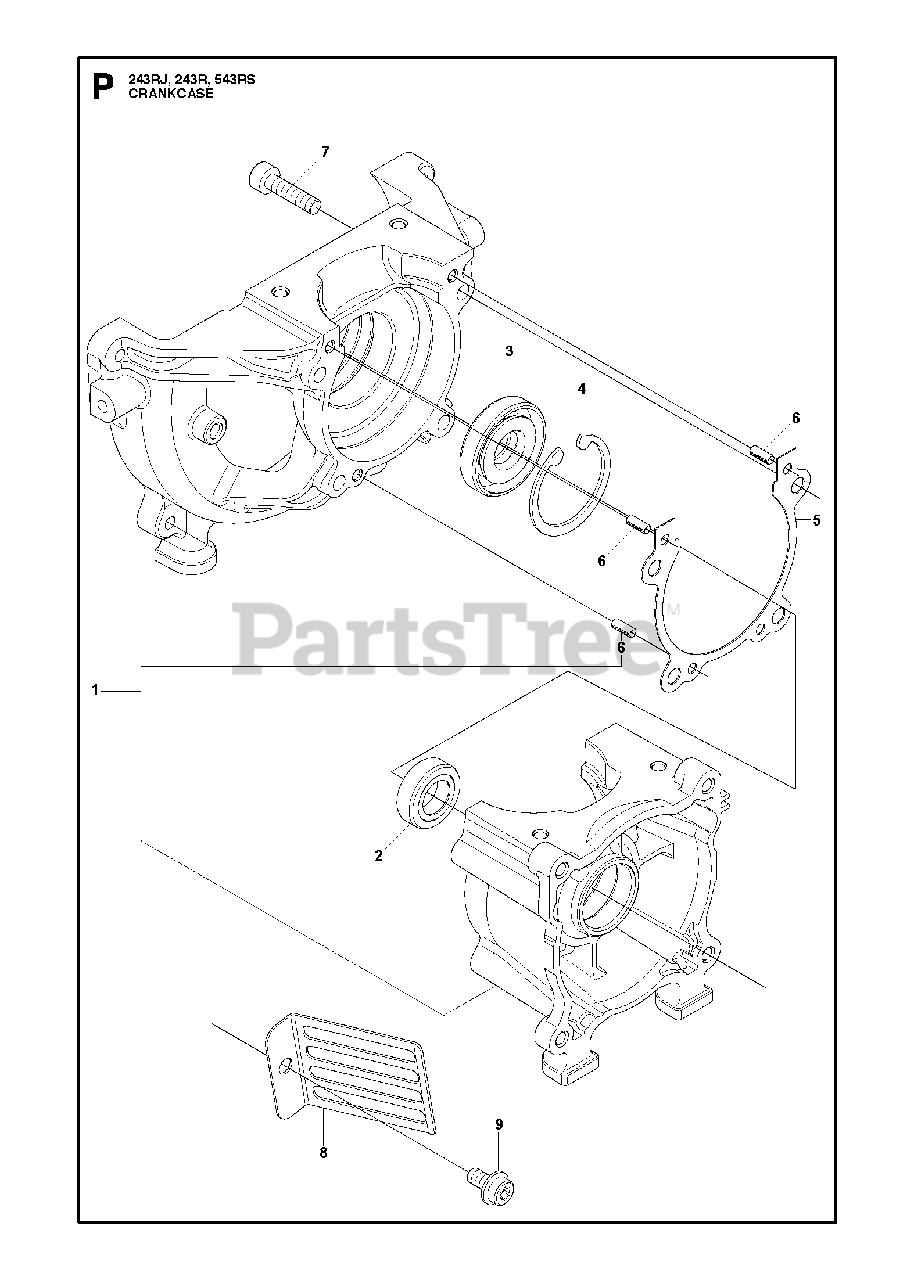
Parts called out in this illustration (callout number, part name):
1	CRANKCASE ASSY
6	PIN
7	BOLT M5X20 T27
9	BOLT (RPLS T495051010-11)
